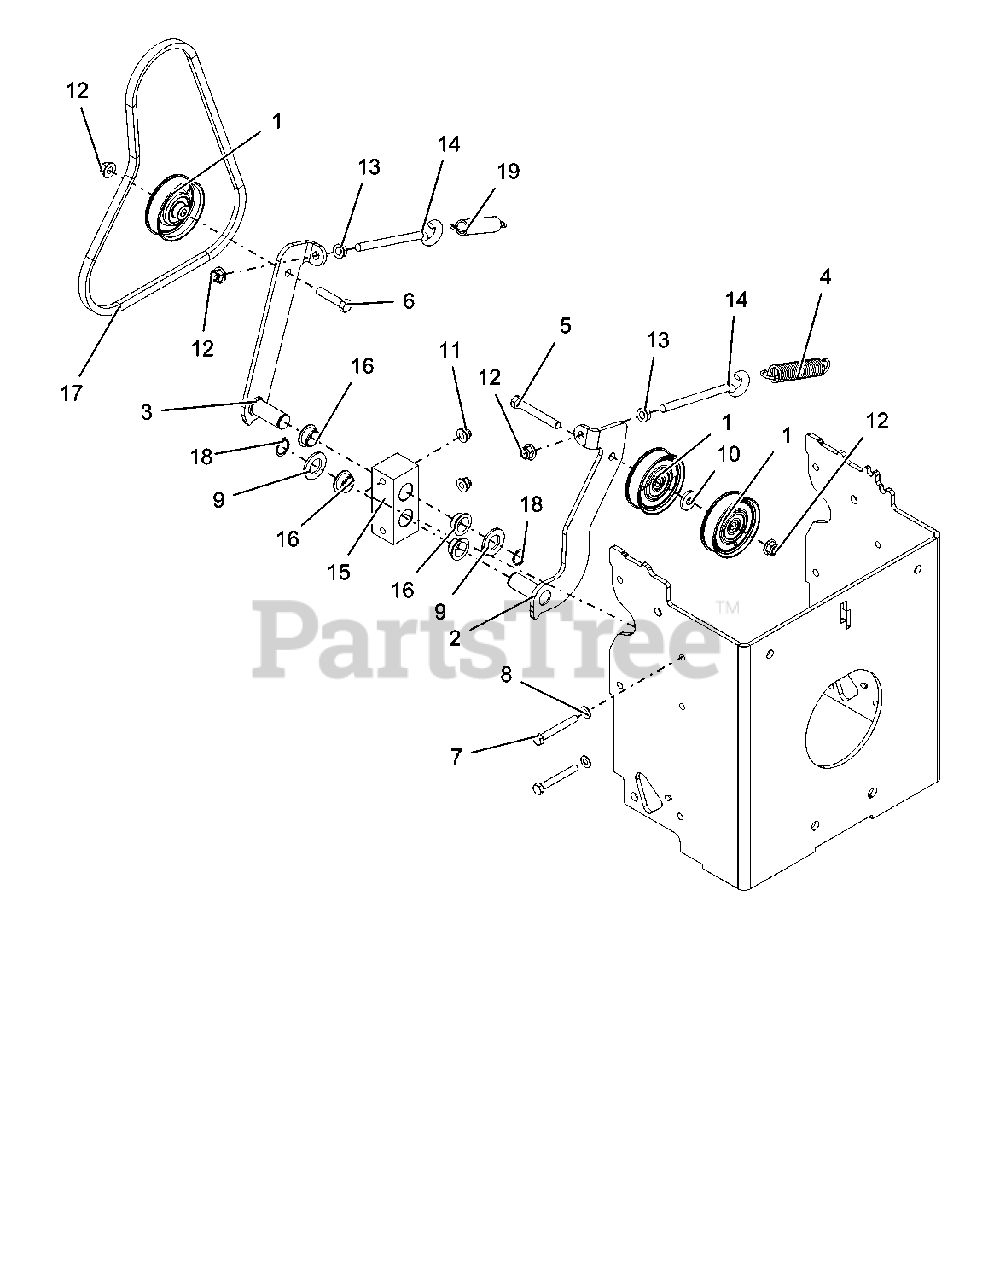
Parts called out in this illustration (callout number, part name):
1	IDLER, FLAT - 3.05" X .75"
2	WLDMT, TENSIONER PTO BELT-RED
3	WLDMT, TENSIONER TRANS BELT-RED
4	SPRG, EXTENSION
5	BLT, HEX 0.375-16X2.75 GR5 ZC120
6	BLT, HEX 0.375-16X1.75 GR5 ZC120
7	BLT, HEX M8-1.25X65 GR8.8 ZC120
8	WSHR-FL-STL .323X.625X.062 ROHS
9	WSHR-FL-STL .196X.500X.06 ROHS
10	WSHR-FL-STL .438X1.00X.160 YWZC
11	NUT, LK-NYL-FLG M8-1.25 GR8.8 ZC120
12	NUT, LK-NYL-FLG .38-16 GR5 ZC120
13	NUT, FLG-SPNLK .375-16 GR5 ZC120
14	BOLT, EYE .38-16X4.50 .62DIABZ
15	BLOCK, BRG IDLER-RED
16	BSHG, IDLER EP BB2012
17	V-Belt, HA-DOUBLE CLUTCHING COVER
18	SNAP RING, .781 X .042 EXT
